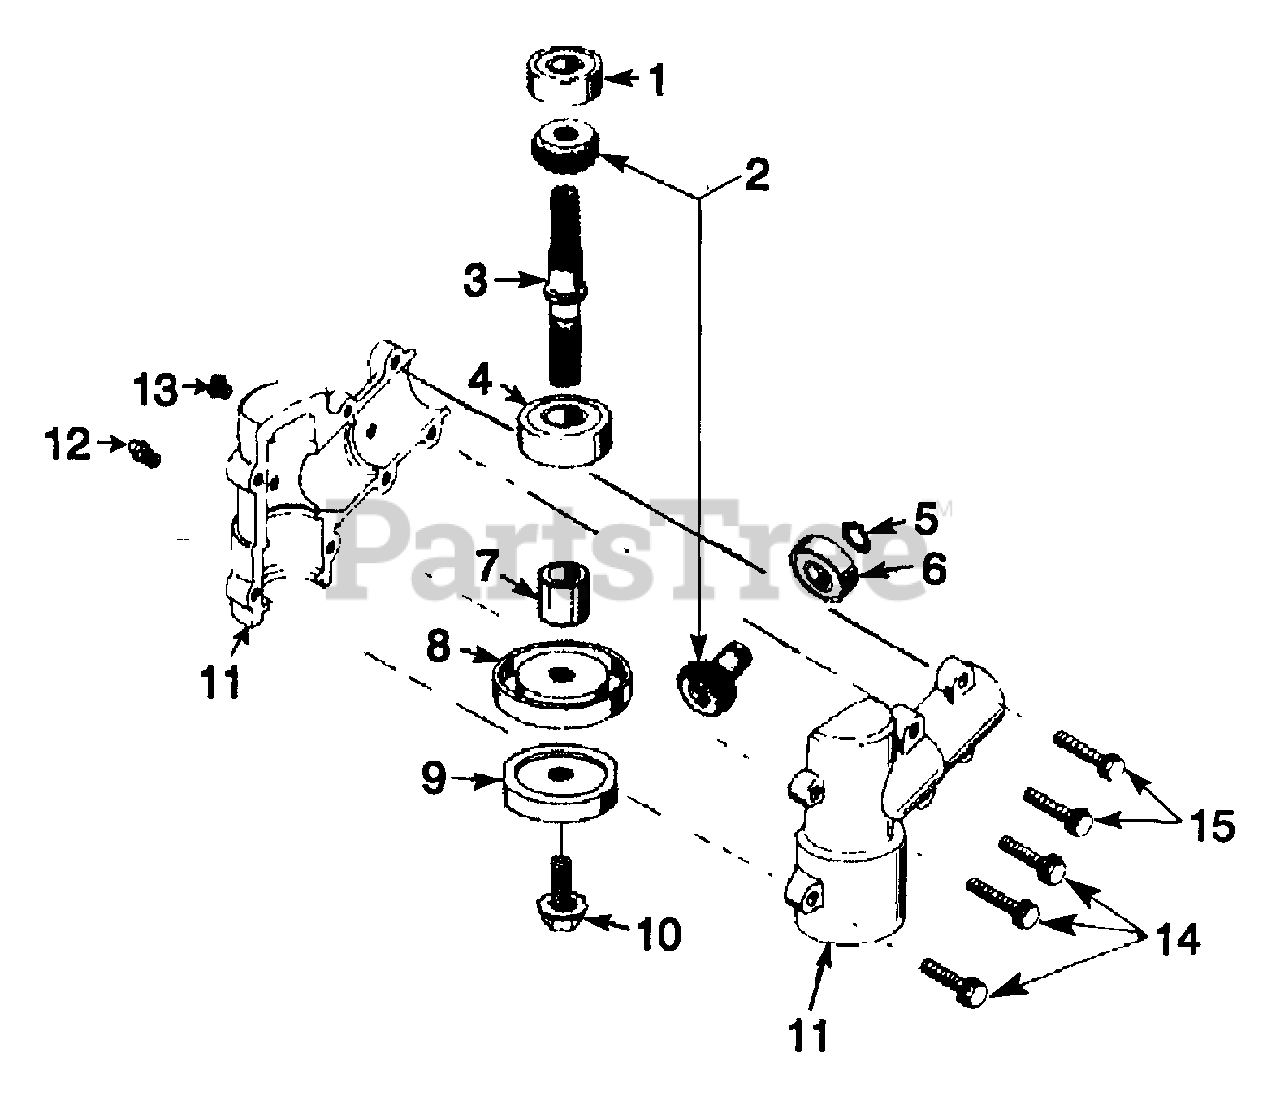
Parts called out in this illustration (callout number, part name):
1	Bearing
3	Shaft, Gear
4	Bearing
6	Bearing
8	Upper Flange Washer
9	Lower Flange Washer
10	Sems Screw, Blade
11	Housing Set
12	Fitting, Zerk
13	Screw, Self Tapping
14	Screw, Self Tapping
15	Screw, Self Tapping
